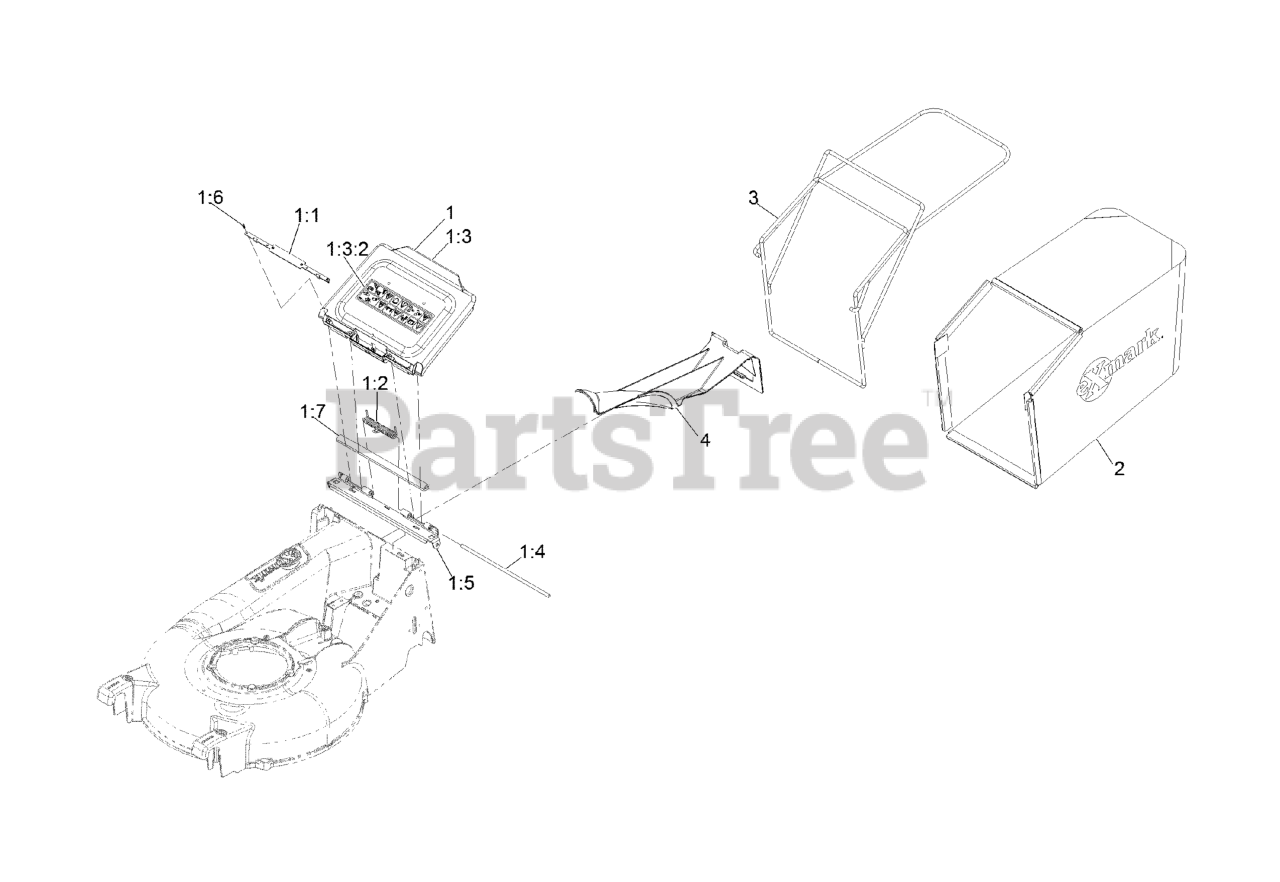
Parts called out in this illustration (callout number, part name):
1	DOOR ASM
1:1	X-REF 126-2628-03
1:2	SPRING-PLASTIC DOOR
1:3	ASM-DOOR & DECAL
1:3:2	DECAL-WARNING
1:4	PIN-DOOR PIVOT
1:5	X-REF TO 126-2636-03
1:6	SCR,TAP,6-19X7/16,PHPH, S
1:7	SEAL-EPDM FOAM BULB
2	BAG-GRASS EC21
3	WLD-BAG FRAME
4	PLUG,MULCH
